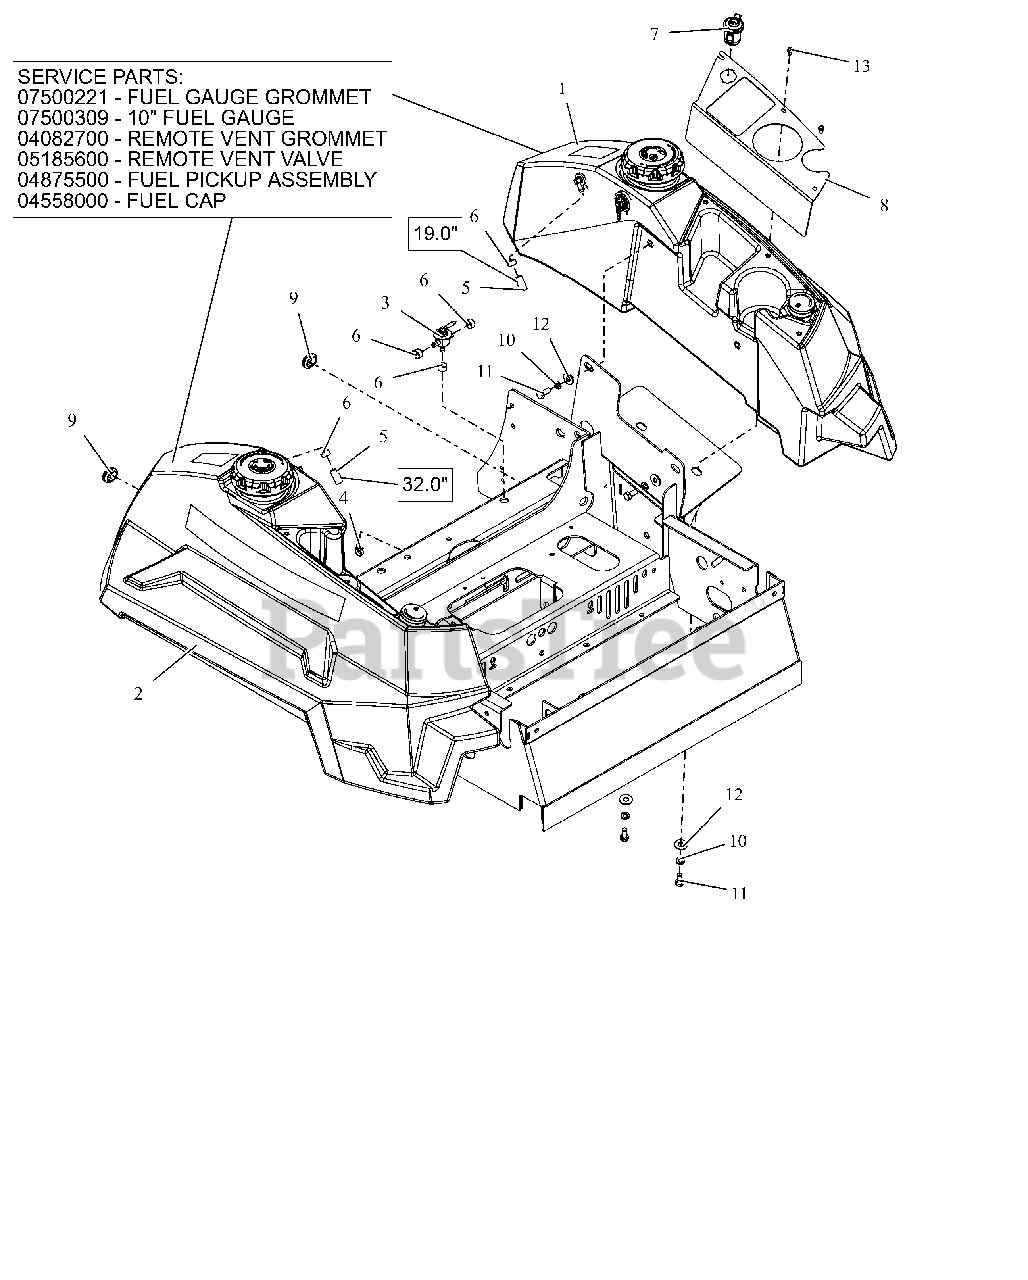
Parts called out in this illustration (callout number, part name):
1	ASM, LH FUEL TANK
1	GROMMET, FUEL GAUGE
1	GAUGE, REMOTE FUEL SEALED 10"
1	GROMMET, REMOTE VENT NITRILE
1	VALVE, COMBINATION VENT 3/16
1	ASSM,LRG TANK FUEL PICKUP LINE
1	CAP, FUEL VENTIN AUTOLOCK
2	ASSY-RH, PT400 FUEL TANK
3	VALVE - FUEL
4	ROUTING CLIP (1/2" ID)
5	HOSE, .25 LOW-PERM BULK GAS
6	CLAMP, FUEL LINE
7	PORT, 12 VOLT POWER
8	CUP HOLDER/POCKET PLATE - RED
9	GROMMET,RUBBER 5/8 ID/1.13 OD
10	WSHR,LK-REG .312X.078 ZCC
11	BLT,HEX .31-18X.75 G5 ZCC
12	WSHR,FLT .375X.875X.083 ZCC
13	SCR-MCH 10-24X.38 HWHSTAINLESS
